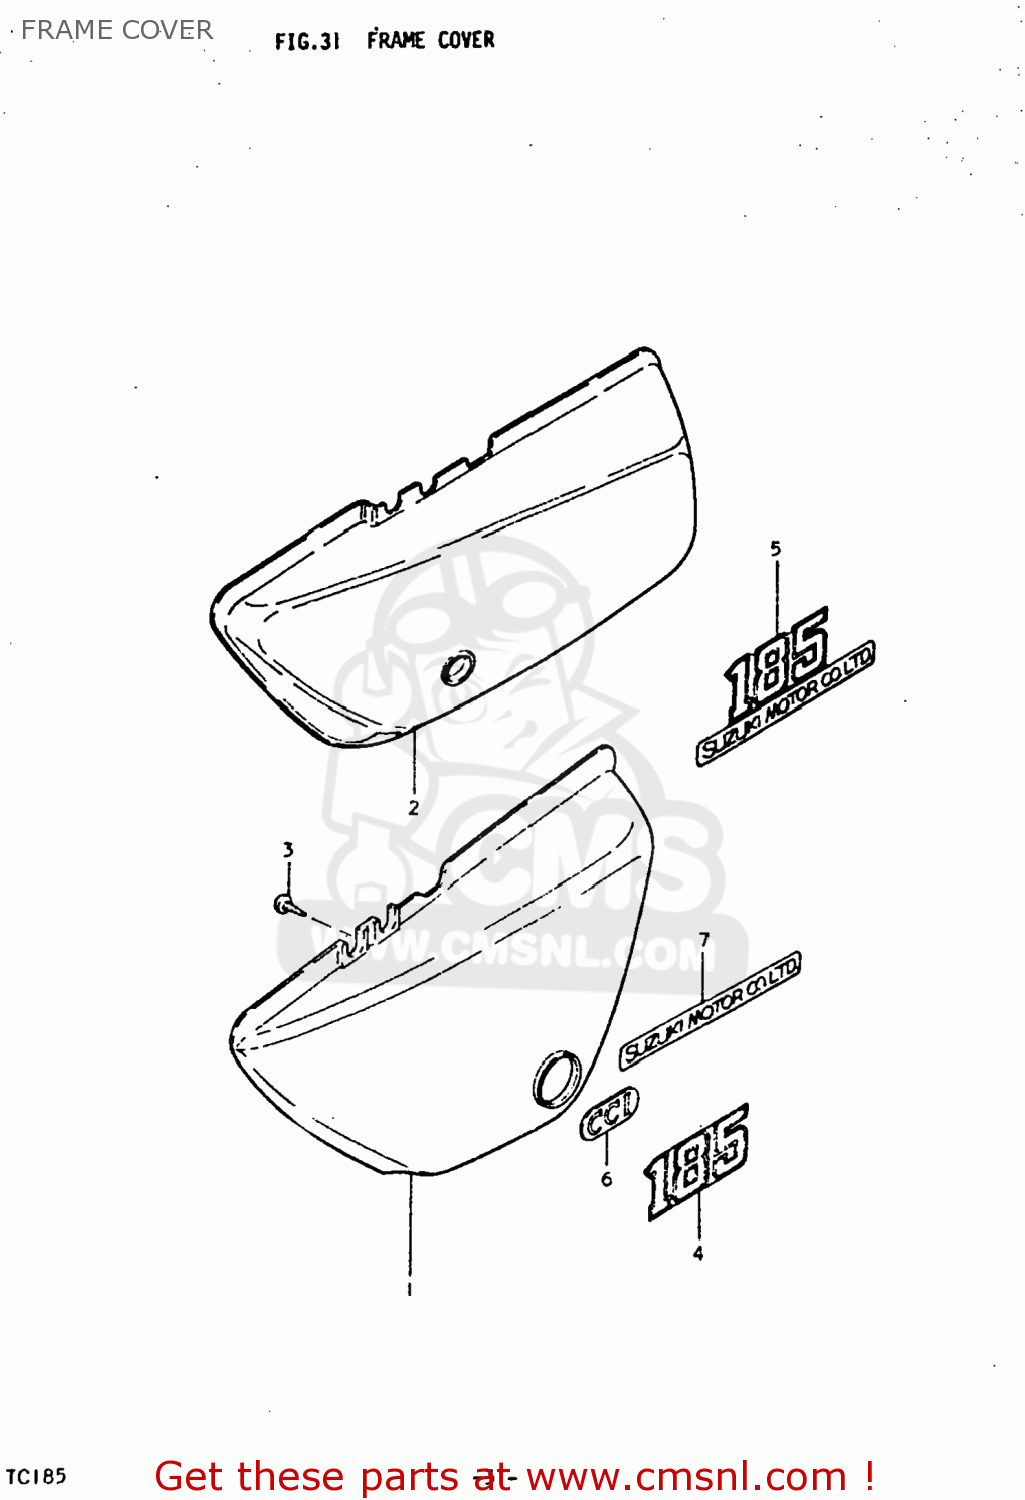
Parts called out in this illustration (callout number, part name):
1	COVER,FRAME,LEFT
2	COVER,FRAME,LEFT
3	SCREW
4	EMBLEM,FRAME COVER
5	EMBLEM,FRAME COVER
6	EMBLEM,CCIS
7	LABEL,COMPANY NAME
